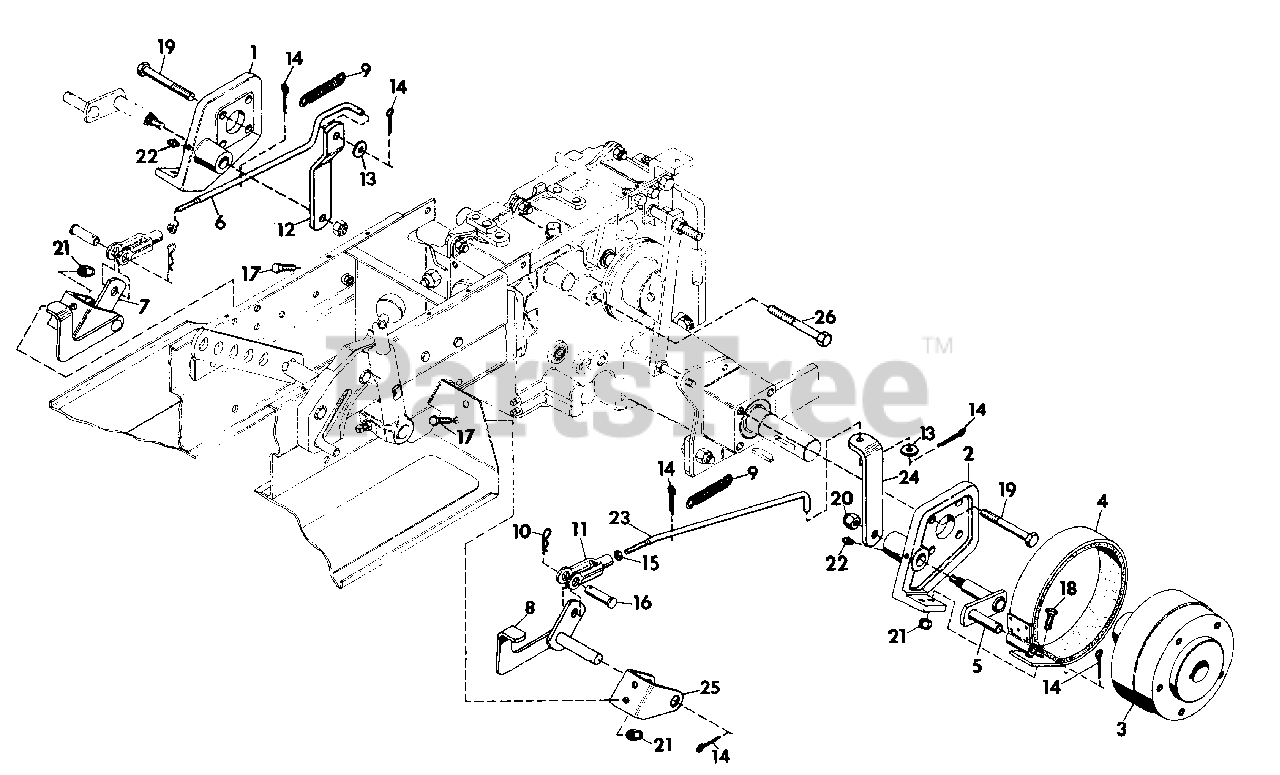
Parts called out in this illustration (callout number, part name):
1	CASTING, BRAKE R.H.
2	CASTING, BRAKE L.H.
3	DRUM, BRAKE
4	ASSEMBLY, BRAKE BAND
5	WELDMENT, PIN-SHAFT
6	ROD, BRAKE
7	WELDMENT, BRAKE PEDAL R.H.
8	WELDMENT, BRAKE PEDAL L.H.
9	SPRING
10	PIN, COTTER HAIR
11	CLEVIS, 3/8-24 ADJUSTABLE
12	LINK
13	WASHER, FLAT .438X1.000X.083
14	PIN, COTTER .09X.62
15	NUT, JAM 3/8-24
16	PIN, CLEVIS .395X.948
17	BOLT, HEX 5/16-18X.75
18	BOLT, HEX 5/16-18X1.25
19	BOLT, HEX 1/2-13X4.00
20	NUT, LOCK 3/8-24
21	NUT, LOCK 5/16-18
22	FITTING, LUBE 1/4-28
23	ROD, BRAKE R.H.
24	LINK
25	BRACKET, BRAKE PEDAL
26	BOLT, HEX 1/2-13X3.25
